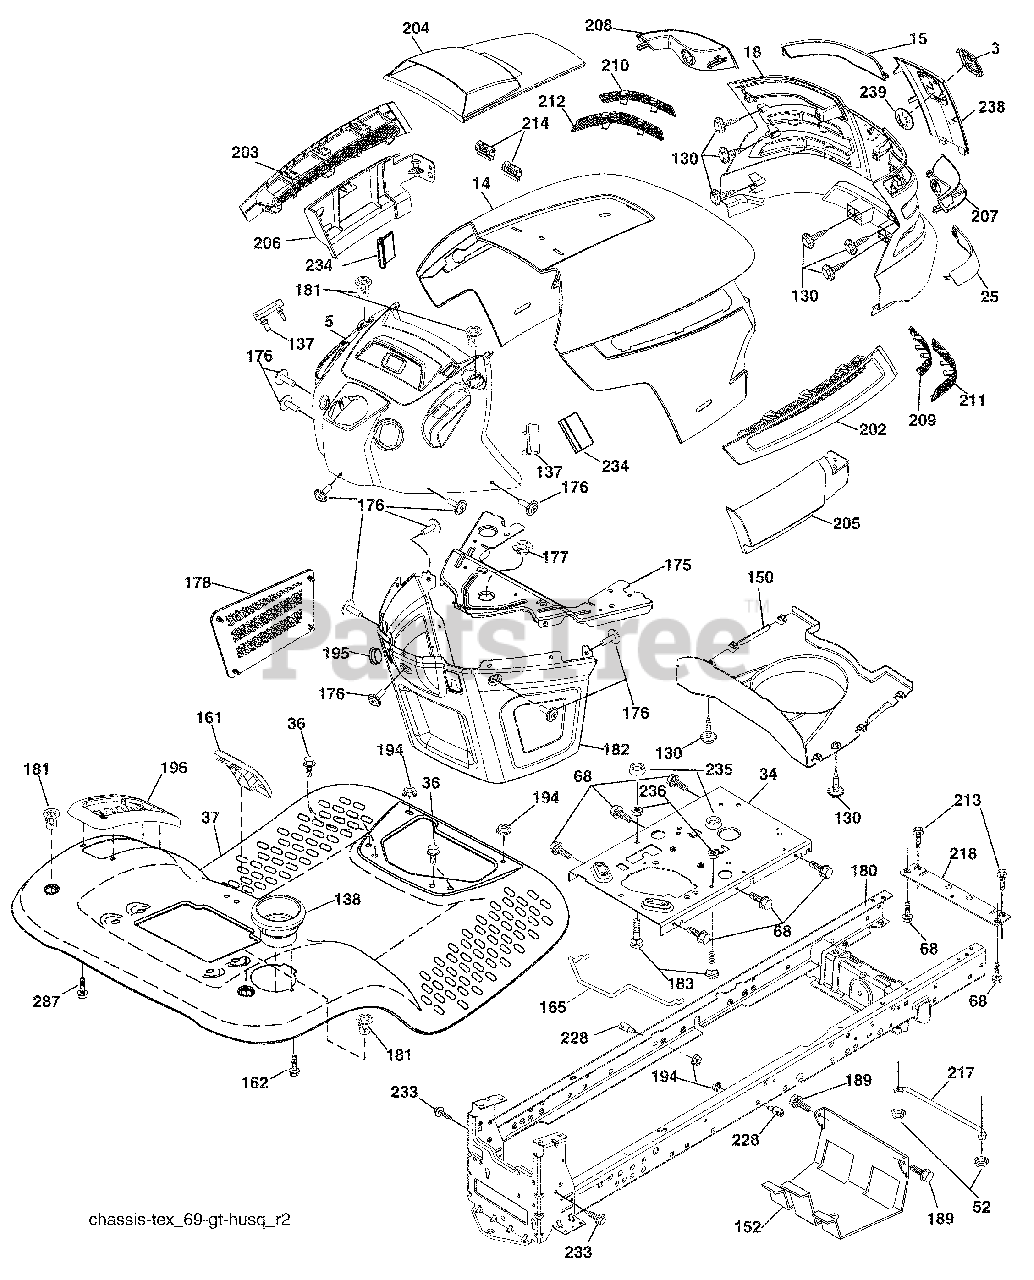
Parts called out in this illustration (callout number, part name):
3	Logo
14	Hood
18	Grille Asm.
34	Plate Engine
36	Screw 5/16-18 x 3/4
52	Nut Lock 5/16-18
68	Screw 5/16-18 x 1/2
130	Screw #10 x 0.750 ROS Thread
137	Bumper Dash
138	Cupholder
152	Shield Browning
161	Window Fuel
165	Support Tank Rear
175	Crossmember
176	Screw 10-24 x 5/8
177	Bushing Steering
178	Cargo Net Asm.
180	Chassis
181	Bushing Mtg. Fender Crgo
182	Dash Lower
183	Bolt Fin Hex 5/16-18 unc x 1-1/4
189	Screw 5/16-18 x 3/4
194	Nut Lock Hex Flange 5/16-18
195	Plug Hole Dash Lower
196	Console Asm. Deck Lift
202	Vent Side Hood RH
203	Vent Side Hood LH
204	Vent Top Hood
205	Skirt Hood Side RH
206	Skirt Hood Side LH
209	Insert Hex Top RH
210	Insert Hex Top LH
211	Insert Hex Bottom RH
212	Insert Hex Bottom LH
213	Bolt 5/16-18 unc x 3/4
214	Clip Retainer Tinner
218	X-Piece Hood Stop
228	Stud Fastener
233	Bolt Shoulder
234	Bumper Hood
235	Spacer Fender
236	Nut Lock 5/16-18 unc
287	Screw Hex WASHEAD 1/4-20 x
